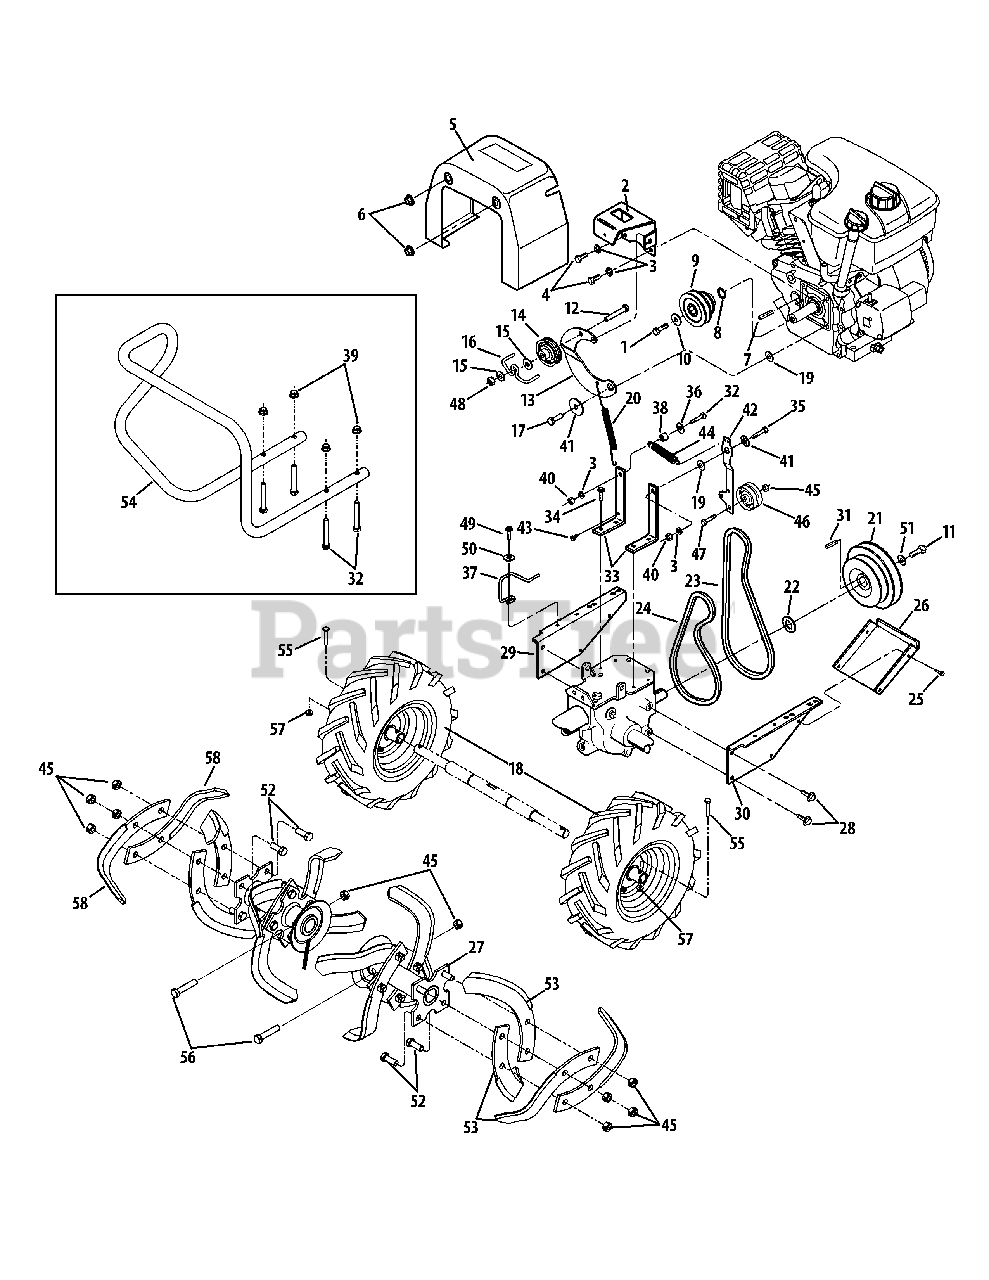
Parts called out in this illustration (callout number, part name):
1	Hex Screw, 3/8-24 x 225 (A)
1	Screw, 5/16-24 x 125 (B)
2	Clutch Cable Bracket
3	Lockwasher, 5/16
4	Hex Head Screw, 5/16-24 x 1/2
6	Flange Lock Nut, 5/16-18
7	Key, 3/16-2 (A)
7	Key, 3/16 x 15 (B)
9	Engine Pulley
10	Belle Washer, 344 x 10 x 063 (A)
10	Belle Washer 827 x 331 x 098 (B)
11	Hex Head Screw, 5/16-24 x 125
12	Hex Head Screw, 5/16-18 x 2
13	Reverse Idler Arm
14	Reverse Idler Pulley
15	Flat Washer, 5/16
16	Wire Formed Belt Guide
17	Hex Head Screw, 5/16-24 x 1
18	Wheel Assembly, 13 x 5 x 6
19	Flat Washer, 1-1/8
20	Reverse Return Spring
21	Transmission Pulley
22	Support Washer
23	Reverse Clutch Belt
24	Forward Clutch Belt
25	Self-tapping Screw, #10-32 x 1/2
26	Belts/Pulleys Guard
28	Hex Flange Screw, 5/16-18 x 3/4
29	Engine Support Bracket (left side)
30	Engine Support Bracket (rt side)
31	Key, 3/16 x 150
32	Hex Head Screw, 5/16-18 x 2-1/4
33	Mounting Bar
34	Hex Flange Screw, 5/16-18 x 75
35	Hex Head Screw, 5/16-18 x 1-1/2
36	Flat Washer, 5/16
37	Belt Guide
38	Pivot Bushing
39	Hex Lock Nut, 5/16-18
40	Hex Nut, 5/16-18
41	Shoulder Washer
42	Forward Tiller Direction Idler Arm
43	Self-tapping Screw, #10-24
45	Hex Locknut, 5/16-18
46	Forward Idler Pulley
47	Screw, 3/8-16 x 1-3/4
48	Hex Lock Nut, 5/16-18
49	Screw, 1/4-20 x 3/4
50	Flat Washer, 1/4
51	Belleville Washer, 827 x 331 x 098
52	Hex Head Screw, 3/8-16 x 1
55	Hex Head Screw, 1/4-20 x 15
56	Hex Head Screw, 3/8-16 x 2
57	Flange Hex Locknut, 1/4-20
